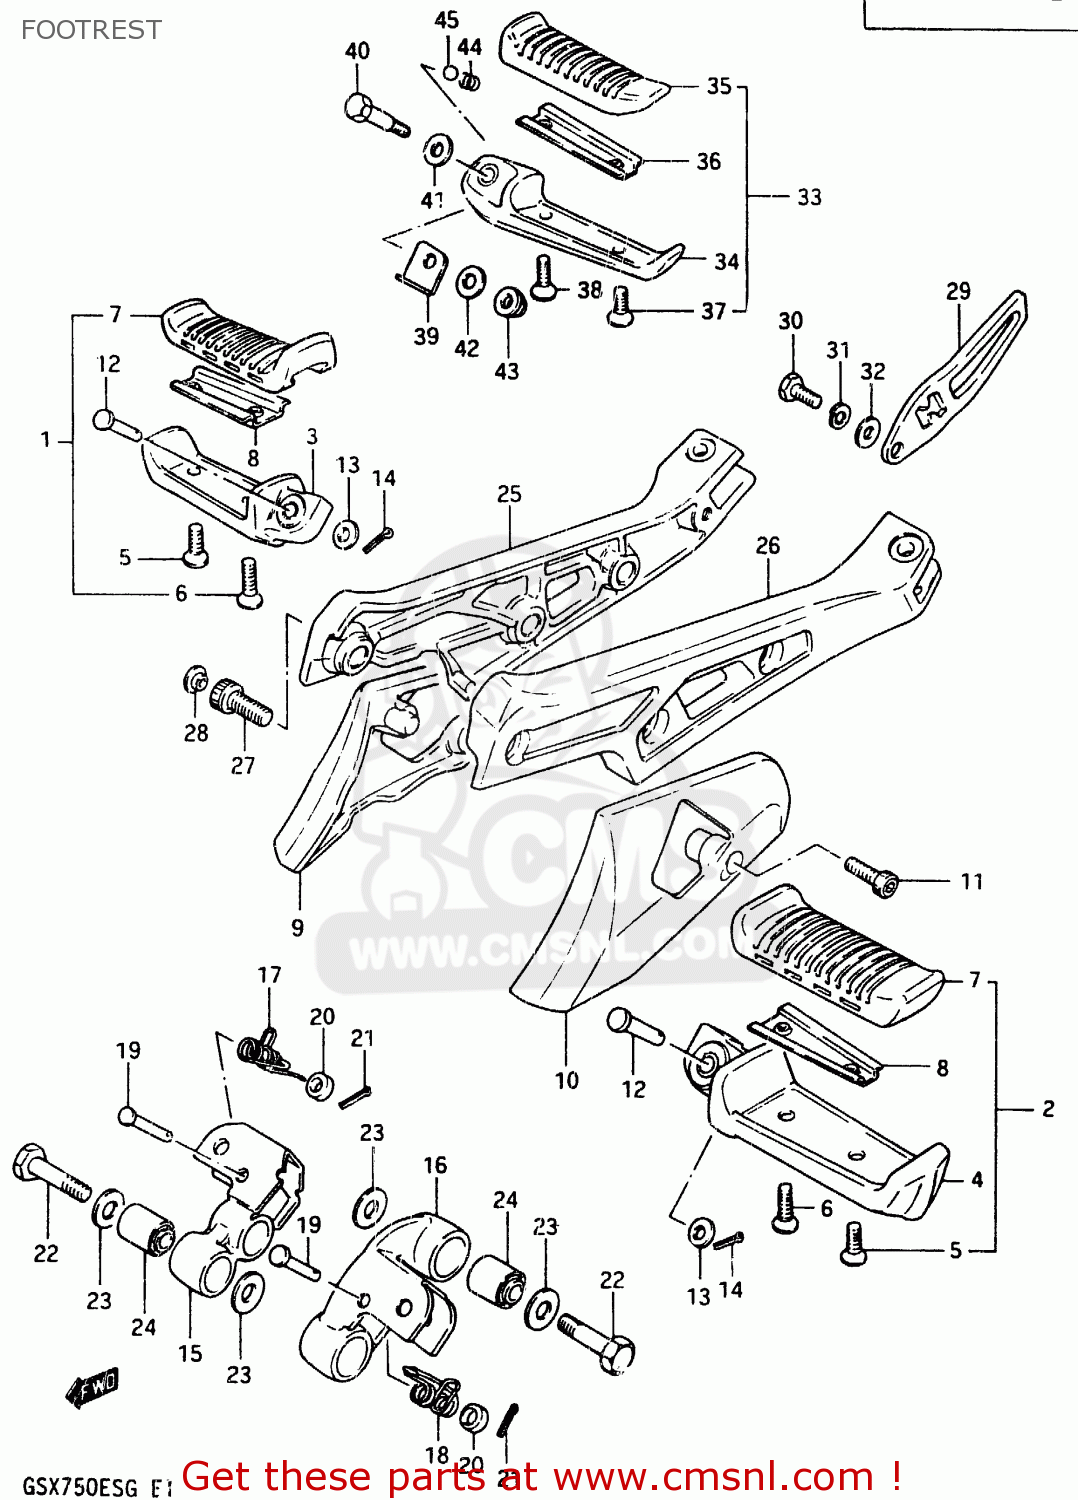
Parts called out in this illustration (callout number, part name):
1	FOOTREST ASSEMBLY,FRONT,RIGHT
2	FOOTREST ASSEMBLY,FRONT,LEFT
3	BAR,FRONT FOOTREST,RIGHT
4	BAR,FR FOOTREST,L
5	SCREW
6	SCREW
7	RUBBER,FOOTREST
8	PLATE,FR FOOTREST RUBBER
9	COVER,FRONT FOOTREST,RIGHT
10	COVER,FRONT FOOTREST,LEFT
11	BOLT
12	PIN
13	WASHER
14	PIN 20X20
15	HOLDER,FRONT FOOTREST,RIGHT
16	HOLDER,FRONT FOOTREST,LEFT
17	SPRING
18	SPRING
19	PIN
20	SPACER (6.5X12X5.5)
21	PIN 20X20
22	BOLT 10X40
23	WASHER(10.5X20X3.2)
24	BUSH
25	BRACKET,MUFFLER,RIGHT
26	BRACKET,MUFFLER,LEFT
27	BOLT 10X25
28	CAP
29	GUIDE,REAR FOOT
30	BOLT,8X16
31	LOCK WASHER
32	WASHER
33	FOOTREST ASSY,PILLION,R
34	BAR,PILLION FOOTREST,LEFT
35	RUBBER,RR FOOTREST
36	PLATE,RUBBER STOPPER
37	SCREW 5X12
38	SCREW 5X16
39	PLATE,SPRING STOP
40	BOLT
41	SHIM(8.2X22X0.2)
42	WASHER
43	NUT
44	SPRING
45	BALL
